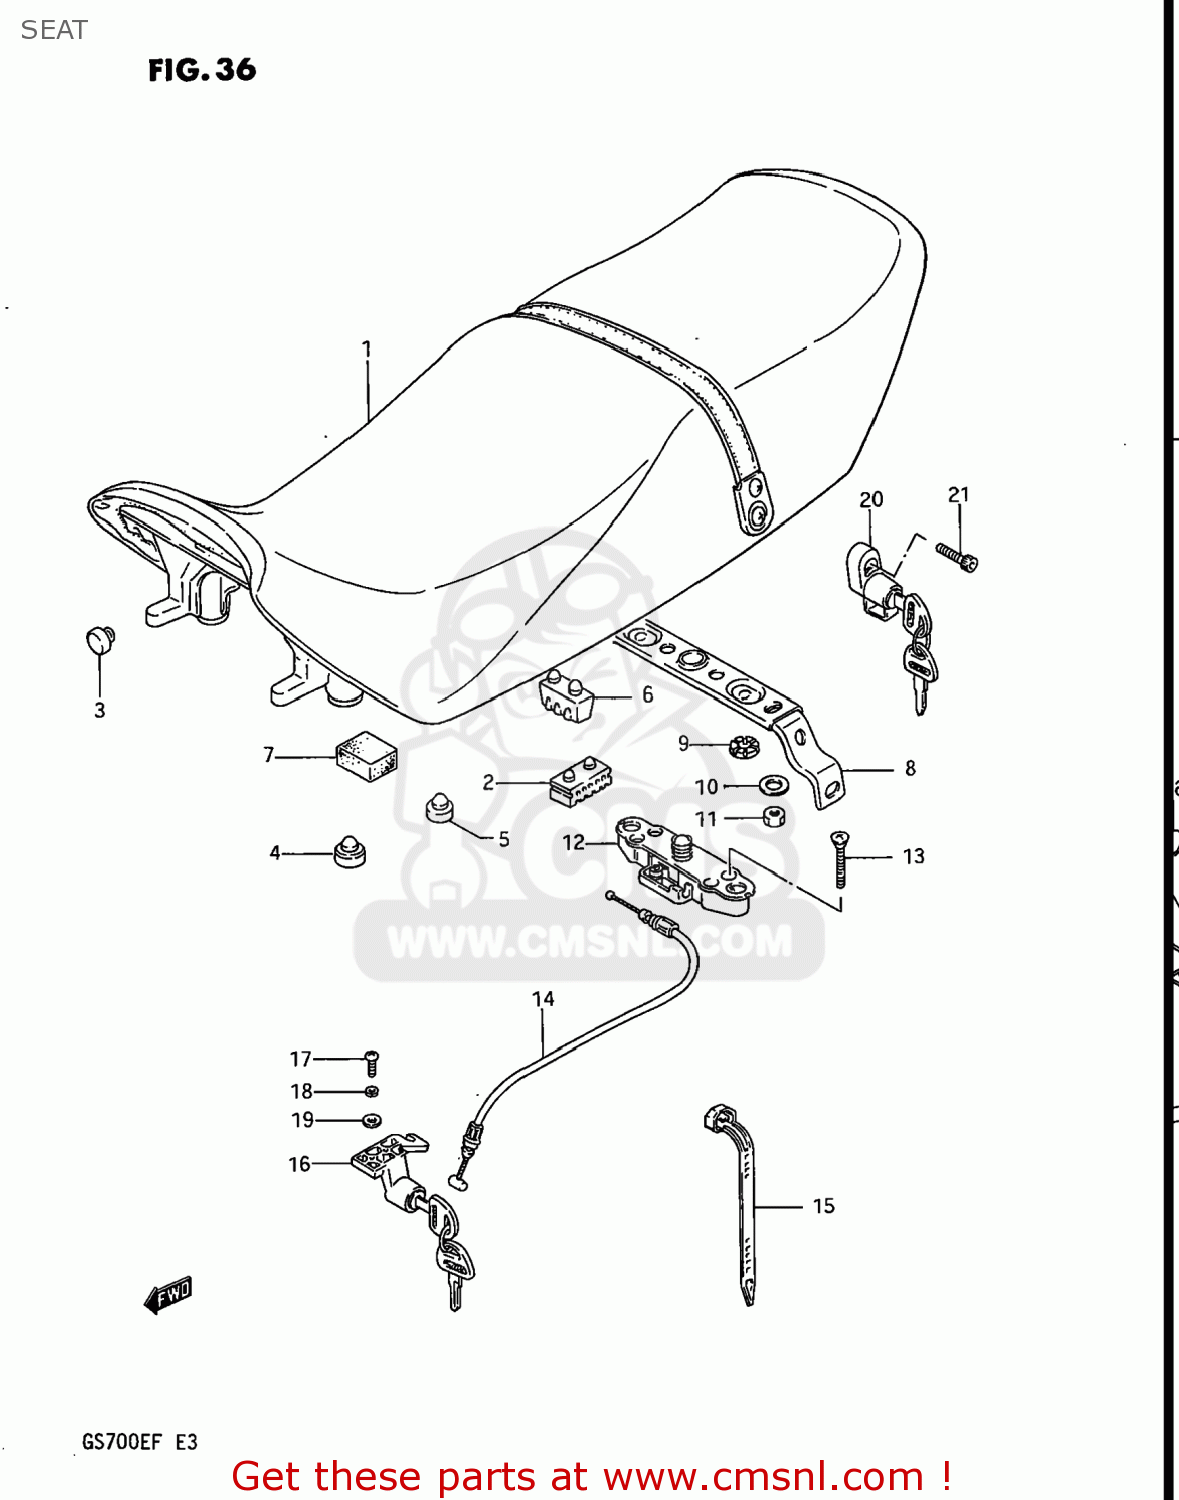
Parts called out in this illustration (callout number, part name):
1	SEAT ASSEMBLY
2	CUSHION,SEAT(40X20X15)
3	CUSHION
4	CUSHION(11.5X22X20)
5	CUSHION
6	CUSHION,SUPPORT(50X25X32)
7	CUSHION,TOOL(40X30X15)
8	STRIKER,SEAT LOCK
9	CUSHION,STRIKER
10	WASHER, LOWER
11	NUT
12	WEATHERSTRIP,SEAT
13	LOCK ASSY,SEAT STRIKER
14	SCREW,6X30
15	CABLE,SEAT LOCK
16	CLAMP(L:165)
17	LOCK ASSEMBLY,SEAT
18	SCREW
19	WASHER,LOCK
20	WASHER,5MM
21	LOCK SET
22	BOLT
